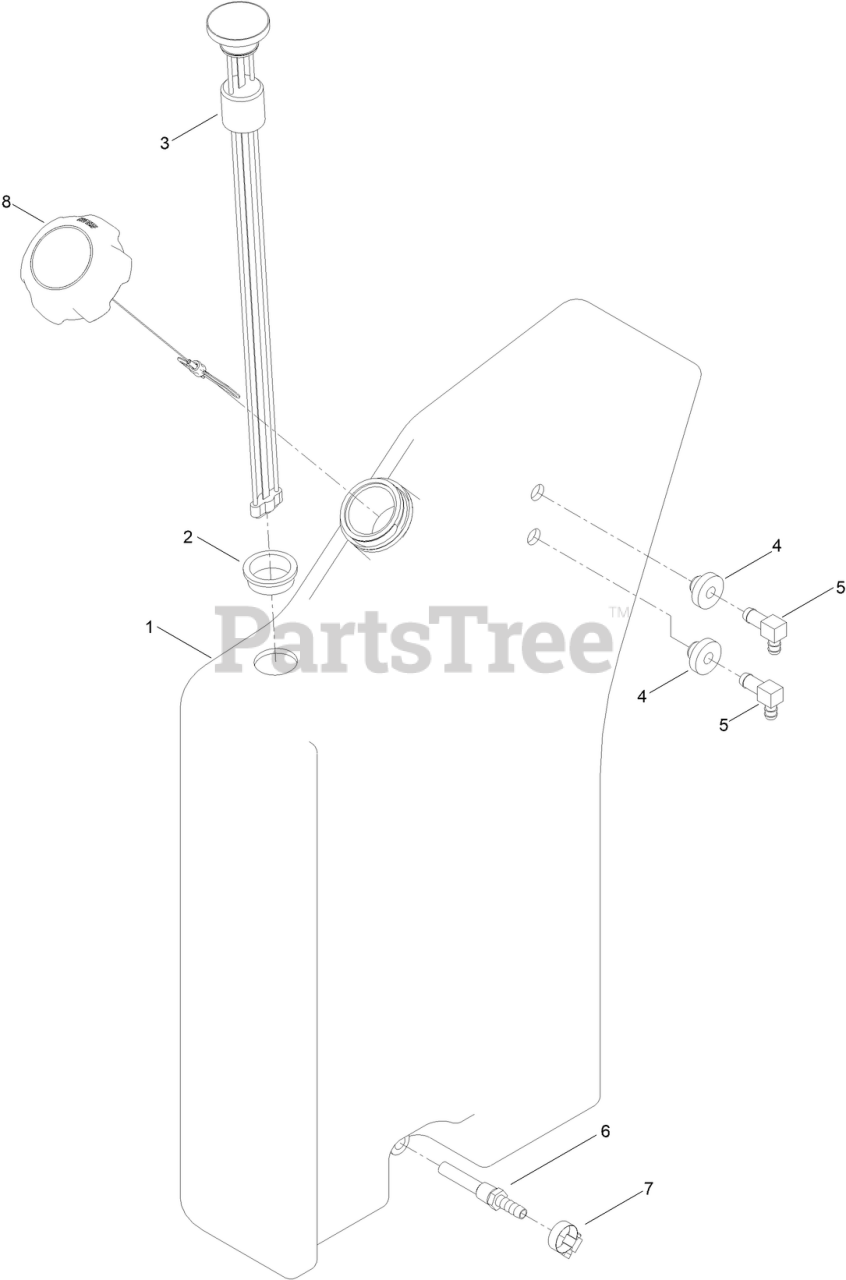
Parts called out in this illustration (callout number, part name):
1	FUEL TANK ASM
2	GROMMET
3	GAUGE-LEVEL, FUEL
4	BUSHING
5	FITTING-ELBOW, 90 DEG
6	FITTING-STRAINER
7	CLAMP-HOSE
8	CAP-DIESEL,
